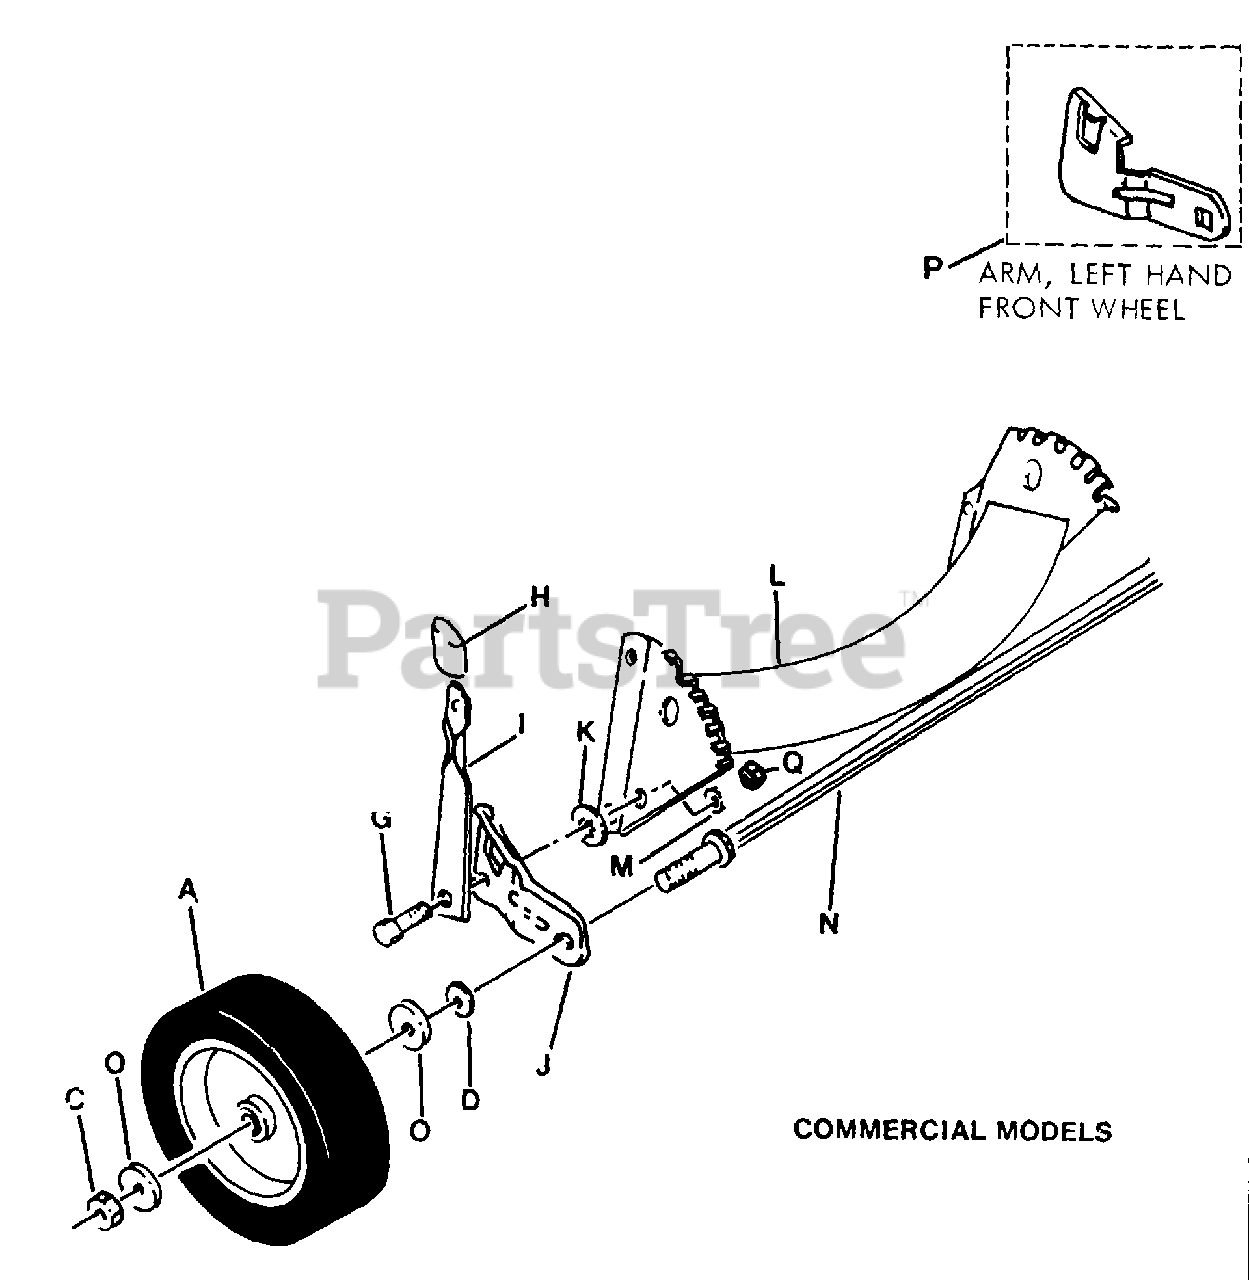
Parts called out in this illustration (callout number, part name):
A	WHEEL, FRONT 7 x 1.50 - 21500C & 21500PC (steel rim)
C	NUT, 7/16F HEX LOCK
D	WASHER, SPRING
G	SCREW, SHOULDER 5/16-18 x 1"
H	GRIP, HEIGHT LATCH
I	LATCH, HEIGHT
J	ARM, RIGHT HAND FRONT WHEEL
K	RETAINER, BOLT
L	BRACKET, FRONT WHEEL -- STRUCTURE
M	LOCKWASHER, 5/16 INTERNAL TOOTH
N	AXLE, FRONT WHEEL
O	CAP, HUB
P	ARM, LEFT HAND FRONT WHEEL
Q	NUT, 5/16-18 HEX
